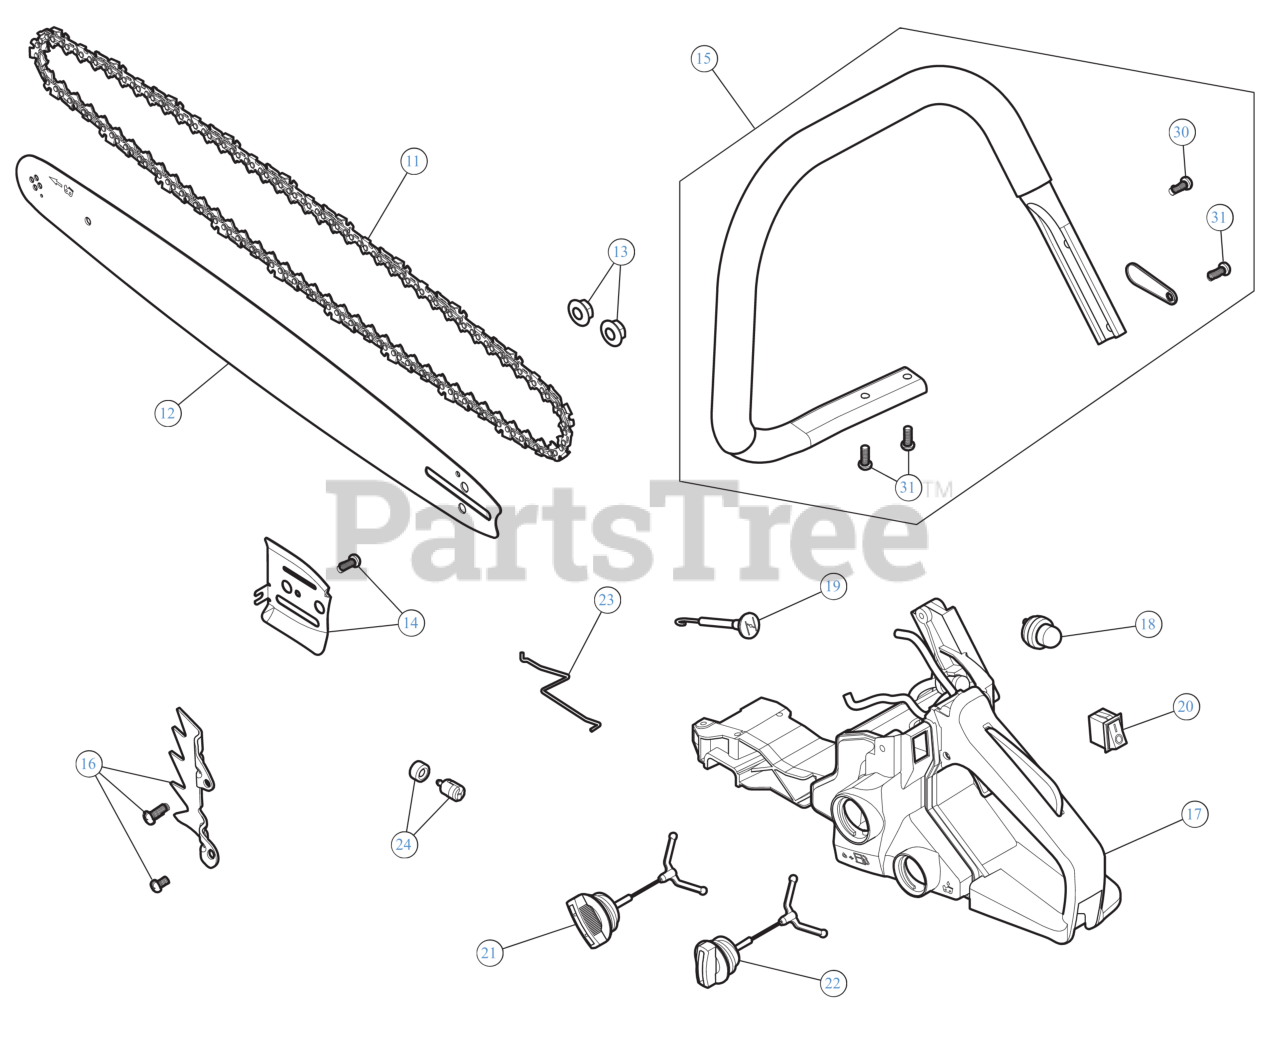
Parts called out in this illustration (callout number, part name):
11	14" CHAIN
11	14" CHAINSAW CHAIN
11	16" CHAIN
11	16" CHAINSAW CHAIN
11	CHAIN 18" TRILINK
12	14" Guide Bar
12	16" Guide Bar
12	18" Guide Bar
13	BAR NUT M8
15	CHAINSAW HANDLE
16	SPIKE PLATE
18	PRIMER BULB
19	CHOKE LEVER
20	STOP SWITCH
23	THROTTLE ROD
24	FUEL FILTER
